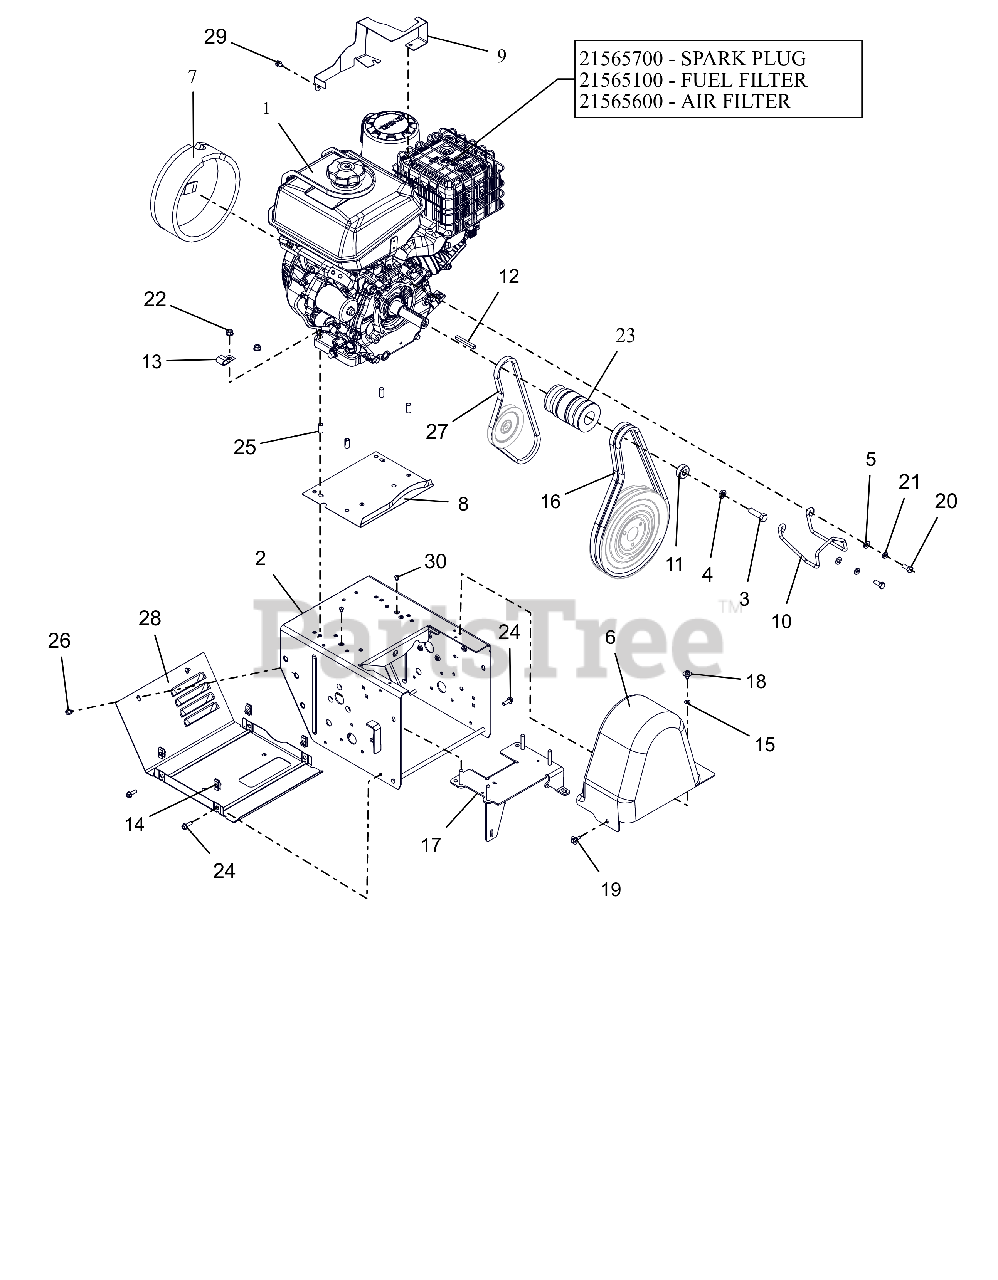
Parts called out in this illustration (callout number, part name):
1	ENGINE, KOHLER - CH395 12V
1	PLUG,SPARK - KOHLER CH395/440
1	FILTER, FUEL (IN TANK)
1	FILTER,AIR - KOHLER CH395/440
2	FRAME, MAIN - PRO (WELDMENT)
3	BLT, HEX .44-20X1.50 G5ZCCEP80
4	WSHR, LK-REG .438X.109 ZCC
5	WSHR,FLT .344X.688X.065 ZCC
6	COVER, BELT-TALL PRO
7	COVER, RECOIL - KOHLER CH395
8	BAFFLE, WATER - LARGE BLOCK
9	BRKT, ENGINE - KOHLER CH395
10	FINGER, BELT
11	BSHG-SPACER .47X1.25X.50
12	KEY .25X.25X2.25
13	J-CLAMP
14	NUT-RTNR .25-20X.56
15	NUT-PUSH .25X.50 O.D.
16	V-BELT, HA-RAW EDGE (SET)
17	BRKT, HYDRO TRANS LG
18	SCR, TAP .25-20X.50 LG HWH ZCC
19	SCR-TAP .25-20X.5 CAPTIVE
20	BLT, HEX .31-24X.750 G5 ZCC
21	WSHR, LK-HVY .312X.097 ZCC
22	NUT,LK-CTR-FLG .31-18 GF ZCC
23	SHEAVE, COMBO HYDRO WHEEL
24	BLT, HWH .25-20X.75 G5 ZCC
25	BSHG-SLV .325X.400X.795
26	SCR-TAP .25-20X.50 HWH ZCC
27	V-BELT, 4L-WRAPPED
28	COVER, BOTTOM - VENTILATED
29	BLT, HEX M6-1.0X10 G10.9 ZCC
30	RVT, POP .1875 ZCC
